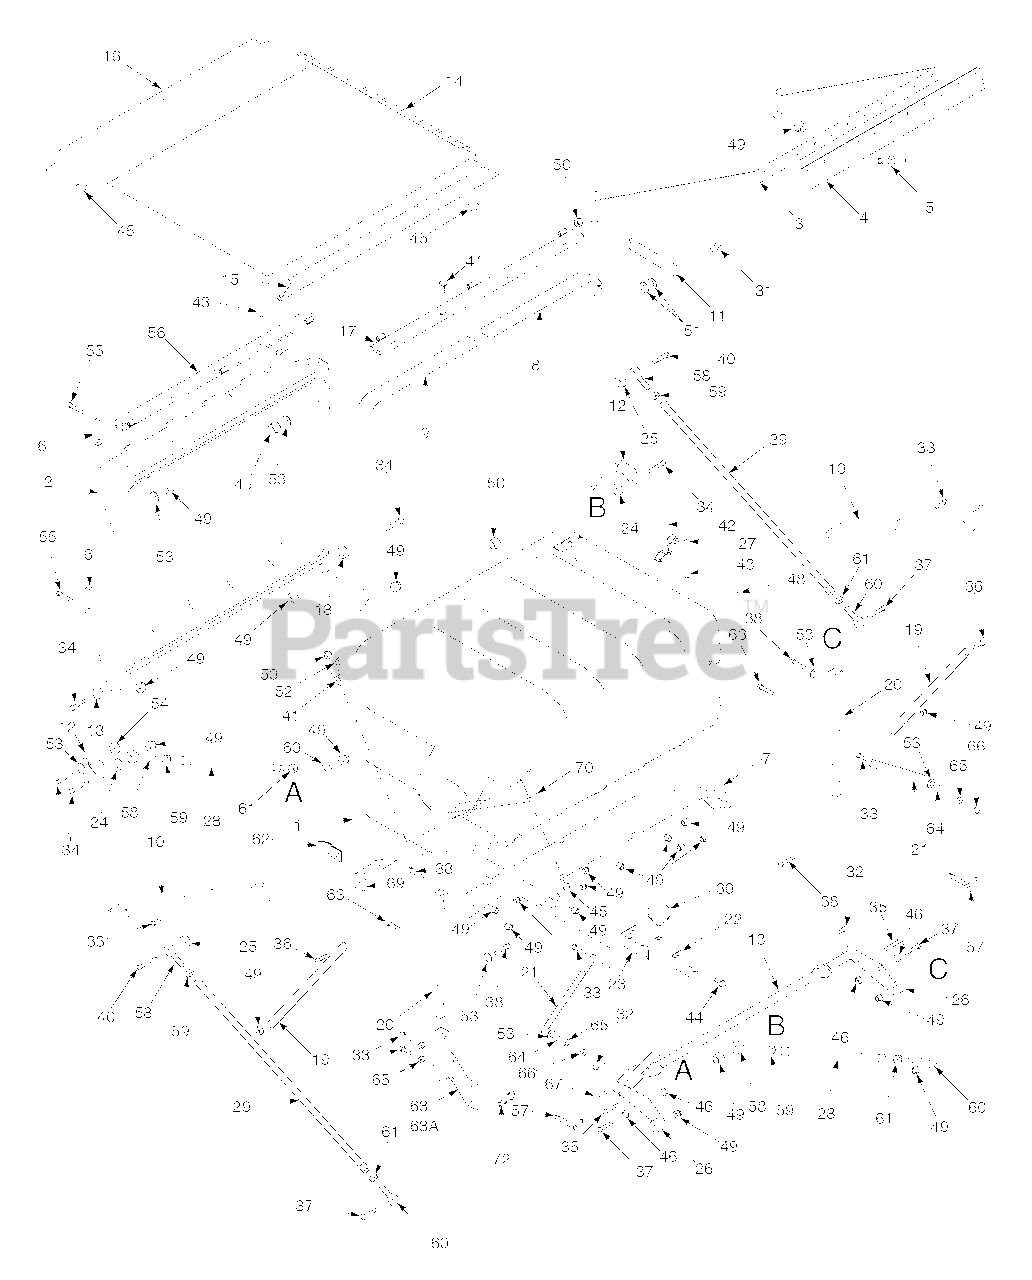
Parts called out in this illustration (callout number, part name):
1	Hopper, GC-STC-CS
2	Door, GC-CS
3	Sweeper Weldment, GC-CS
4	Pad, Rubber
5	Pop Rivet, 3/16 x .652
6	Plate, Stiffener
7	Support Frame, Hopper
8	Hinge Bracket, L.H.
9	Hinge Bracket, R.H.
10	Bracket, Hopper Support
11	Latch, Door Prop
12	Plate, Latch
13	Bellcrank Weldment, Upper
14	Debris Screen Weldment
15	Screen Support Weldment, Rear
16	Screen Support Weldment, Front
17	Hinge Weldment, Hopper
18	Spacer
19	Brace Stiffener, Short
20	Tube, Upright
21	Brace, Engine Mount
22	Latch, Dump Rod Inner
23	Latch, Dump Rod Outer
24	Spacer
25	Spacer
26	Spacer
27	Latch, Hood
28	Linkage Assembly, Lower
29	Linkage Assembly, Upper
31	Bolt, Hex Head 5/16-18 x 1-1/4
32	Bolt, Hex Head 3/8-16 x 3/4"
33	Bolt, Hex Head 3/8-16 x 1"
34	Bolt, Hex Head 3/8-16 x 1-1/2"
35	Bolt, Hex Head 3/8-16 x 1-3/4"
36	Bolt, Hex Head 3/8-16 x 1-1/4"
37	Bolt, Hex Head 3/8-16 x 2"
38	Bolt, Hex Head 3/8-16 x 2-1/4"
39	Bolt, Hex Head 5/16-18 x 3-1/2"
40	Bolt, Hex Head 3/8-16 x 3-1/2"
41	Bolt, Carriage 5/16-18 x 1"
42	Screw, #10-32 x 1/2"
43	Cap Screw, 5/16-18 x 3/4" Serr. Flan.
44	Cap Screw, 5/16-18 x 1" Serr. Flan.
45	Nut, 5/16-18 Serrated Flange
46	Nut, 3/8-16 Serrated Flange
47	Nut, 3/8-16 UNC Jam
48	Nut, #10-32 Elastic Stop
49	Nut, 3/8-16 Elastic Stop
50	Nut, 5/16-18 Elastic Stop
51	Washer, Special Wave
52	Washer, 5/16-.375 x .875 x .083 Flat
53	Washer, 3/8-.931 x .938 x .105 Flat
54	Bushing, Hopper Latch GC-CS
55	Bolt, Hex Head 3/8-16 x 3"
56	Hinge Weldment, Door
57	Lanyard
58	Rod End Male, 3/8-24 L.H. Thread
59	Nut, 3/8-24 UNF L.H. Thread
60	Rod End Male, 3/8-24 R.H. Thread
61	Nut, 3/8-24 UNF R.H. Thread
62	Alignment Bracket, GC-CS
63	Bolt, Hex Head 3/8-16 x 2-1/2"
64	Lock Washer, 3/8-16 Spring
65	Nut, 3/8-16 UNC Zinc
66	Nut, 3/8-16 Center Lock
67	Bolt, Hex Head 5/16-18 1-3/4"
68	Mounting Bracket Weldment, R.H.
68A	Mounting Bracket Weldment, L.H.
69	Bracket, Lower Stiffener
70	Retainer Strip, Hopper
